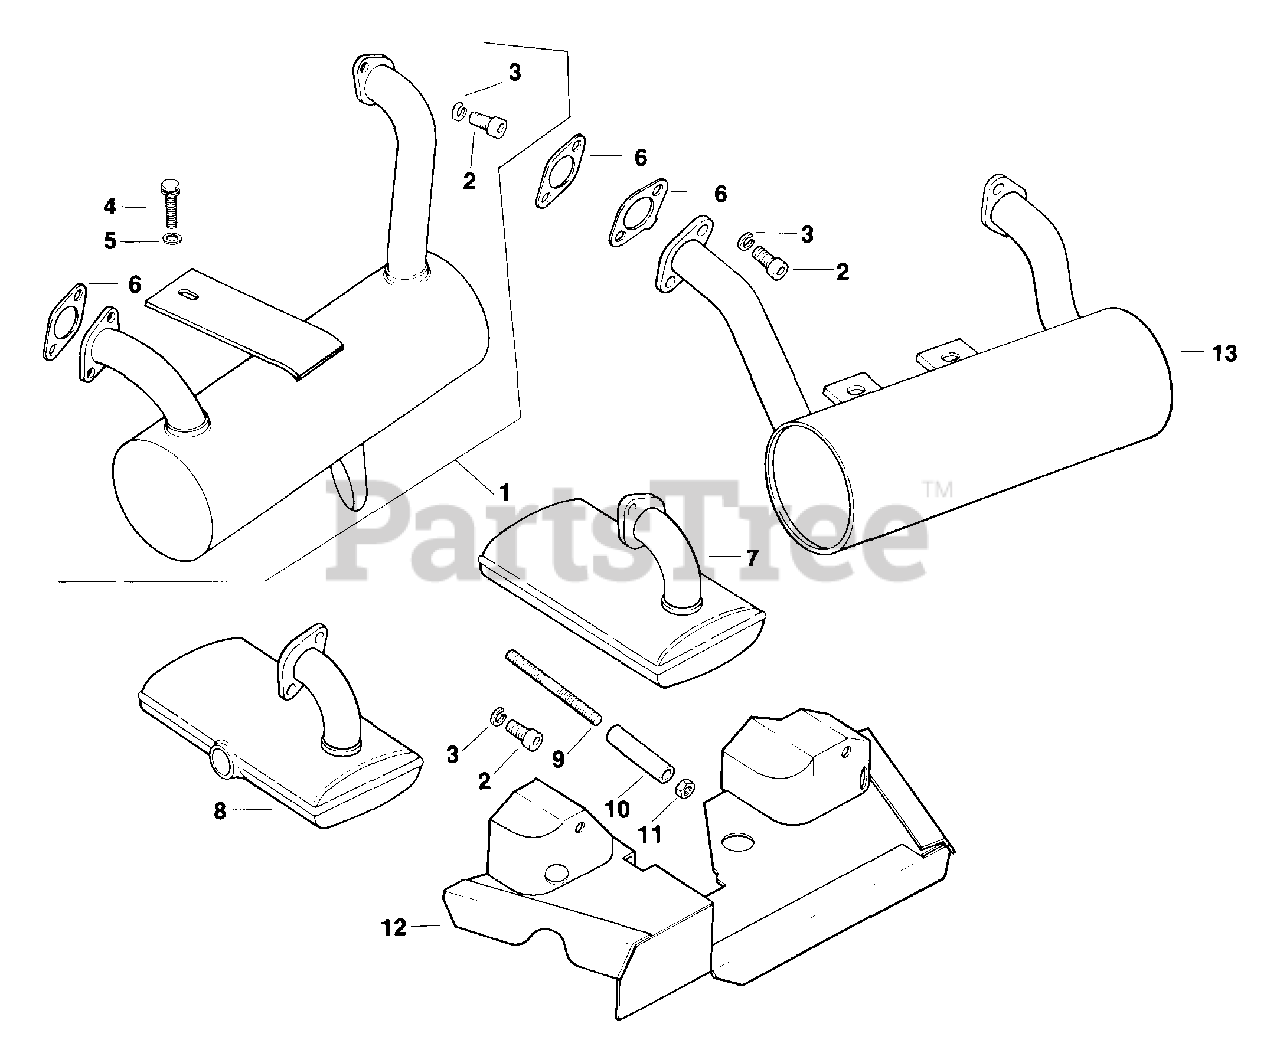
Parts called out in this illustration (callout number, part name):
2	SCREW, HEX SOCKET HEAD CAP USE 25 086 87-S
3	WASHER, SPRING LOCK 5/16"
7	MUFFLER - DISCONTINUED
8	MUFFLER - DISCONTINUED
